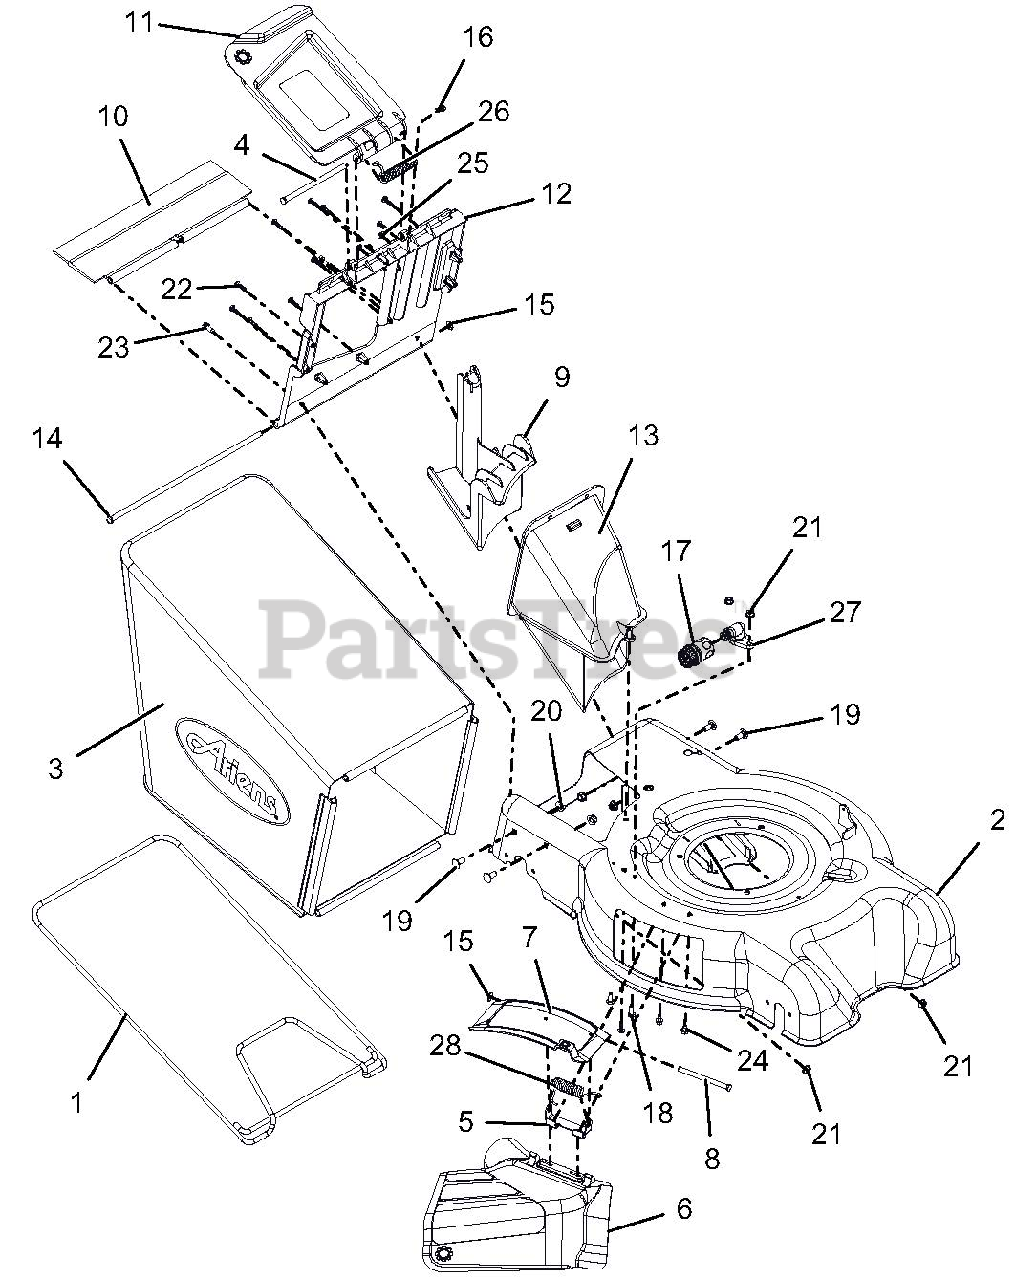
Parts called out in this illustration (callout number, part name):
1	FRAME, BAG
2	WLDMT, ARIENS WP DECK
3	BAGGER, ARIENS LM
4	PIN, 5/16 X 5.80"
5	BRKT, HINGE LM
6	CHUTE, SIDE DISCHARGE - LM
7	COVER, SIDE DISCHARGE - LM
8	PIN, HINGE
9	PLUG, MULCH
10	GUARD, REAR
11	REAR DOOR W/ SAFETY DECAL
12	HANGER, BAG
13	CHUTE, REAR DISCHARGE LM
14	ROD, REAR GUARD
15	NUT-PUSH .312
16	PIN-HAIR INT .08X.18X1.18 YWZC
17	COUPLING, QUICK DISCONNECT
18	BLT-HEX .25-20X.63 GR5 YWZC
19	@BLT-RDHDSQNK .31-18X.75 G5YZ
20	@NUT-LK-TOP-FLG .31-18 YWZC
21	@NUT-LK-TOP-FLG .25-20 YWZC
22	SCR-TAP 12-14X.75PLSTITE @BLZC
23	@SCR-TAP .25-20X.62 HWH TR YWZ
24	@SCR-TAP .25-20X.37 HWH YWZ TR
25	PLUG,5/16 HOLE,.125 MATL PLSTC
26	SG-TORS .120X.68X3.09
27	ASSY, WASHOUT PORT W/ O-RING
28	SPRING, SIDE DISCHARGE DOOR
